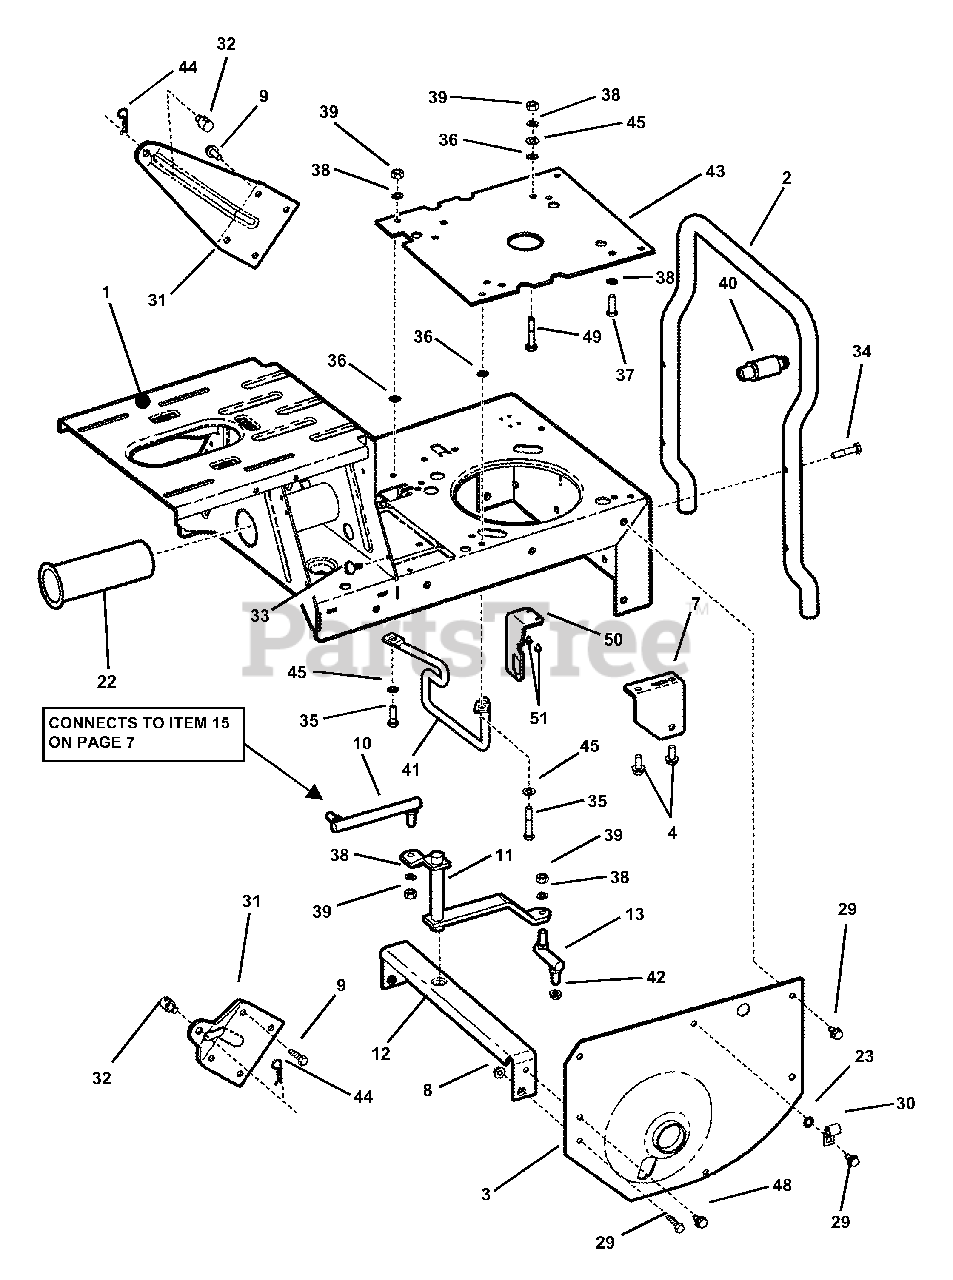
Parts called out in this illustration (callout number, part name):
1	CASE, Main (Weldment)
2	BUMPER, Rear (42" Models)
3	FENDER, Left Hand
4	BOLT, 5/16-18 x 3/4" Hex Flange Lock, Grade 5
7	BRACKET, Drive Support
8	NUT, 5/16-18 Flange Lock
9	SCREW, 5/16-18 x 3/4" Hex Washer Self-Tap
10	LINK, Shift (Long)
11	ARM, Shift (Weldment)
12	BRACE, Cross
13	LINK, Shift (Short)
22	BUSHING, Pivot
23	WASHER, 5/16" Int. Tooth Lock
29	SCREW, 5/16-18 x 5/8" Hex Washer Self-Tap
30	CLIP, Wire
31	WING, Rear Deck
32	SWIVEL
33	FASTENER, Ratchet
34	SCREW, 5/16-18 x 1-1/2" Self-Tapping
35	SCREW, 5/16-24 x 1" Hex Head Cap
36	RETAINER, 5/16 Bolt
37	SCREW, 3/8-16x1" Self Tap
38	WASHER, 5/16" Split Lock
39	NUT, 5/16-24 Hex, Grade 5
40	ASSEMBLY, Oil Drain
41	GUIDE, Belt (42" Models)
42	NUT, 5/16-24 Hex Flange Lock
43	PLATE, Engine
44	HAIRPIN, 3/32 x 1-1/2"
45	WASHER 11/32 I.D.
48	SCREW, 5/16-18 x 3/4" Hex Head Cap
49	SCREW, 5/16-24 x 1-3/4" Hex Head Cap, Grade 5
50	BRACKET, Switch
51	SCREW, #10-32 x 1/4" Hex Washer Head, Self-Tap
